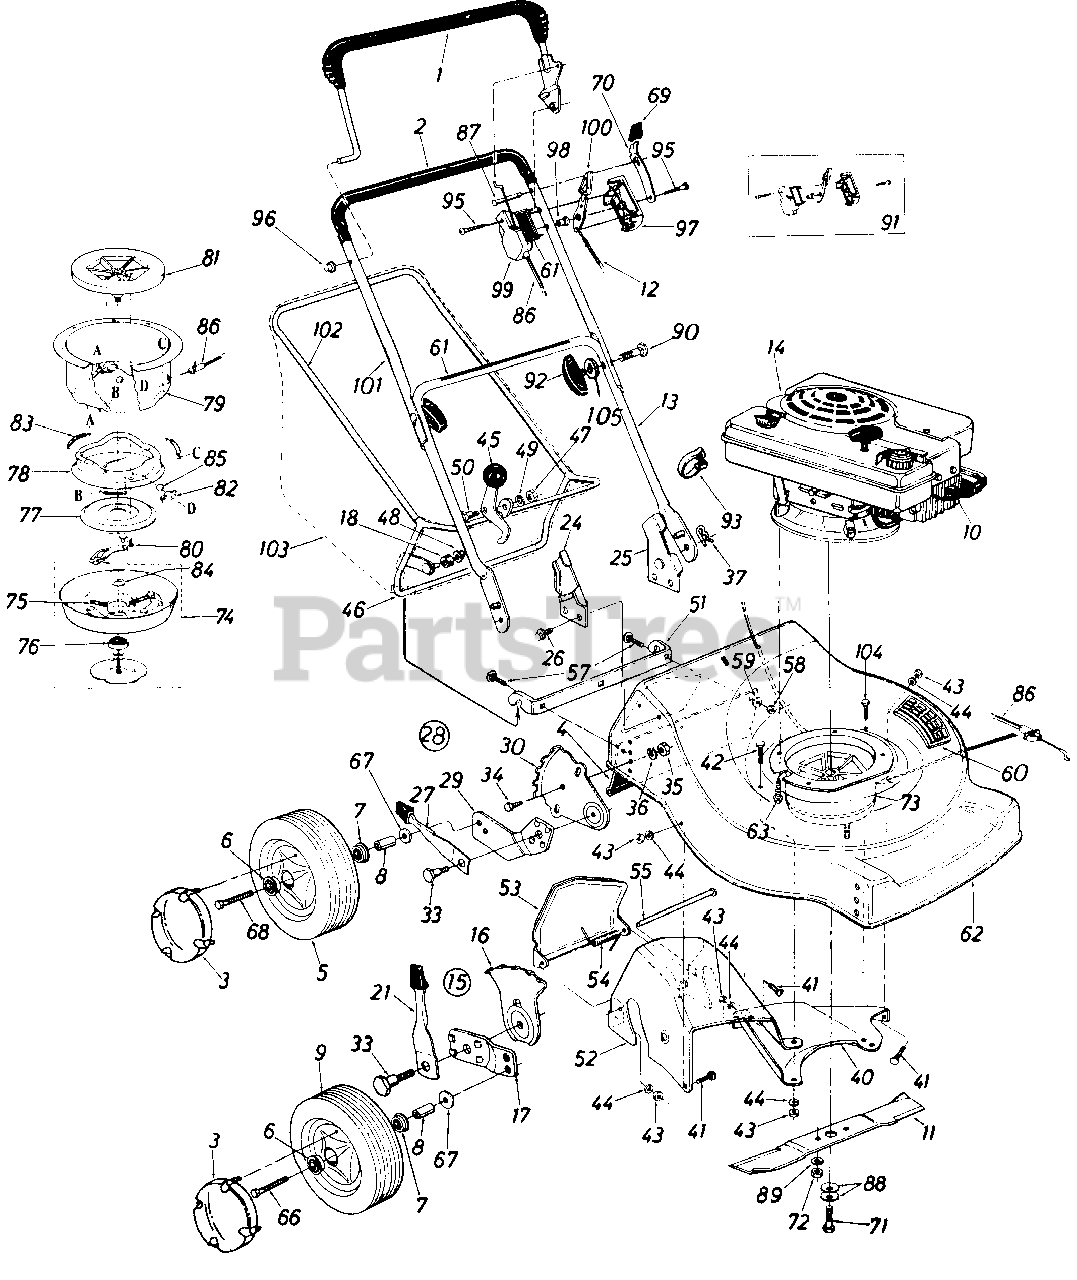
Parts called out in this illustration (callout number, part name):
1	Control Handle Ass'y. L.H.
3	Hub Cap
4	Rear Flap Ass'y.
5	Rear Wheel Ass'y. 8 x 1.75
6	Ball Bearing 3/8" I.D.
7	Ball Bearing 1/2" I.D.
8	Spacer 3/8" 1 .D.
9	Front Wheel Ass'y. 8 x 1.75
10	Spark Plug Boot
11	20" Blade
12	Throttle Wire 43"
13	Lower Handle
15	Height Adj. Ass'y. R.H.
16	Front Index Plate
17	Front Pivot Bar
18	Plastic Roller
21	Spring Lever w/Knob
24	Handle Brk't. Ass'y. R.H.
25	Handle Brk't. Ass'y. L.H.
26	Hex Wash. Hd. AB-Tap Scr. 1/4" x .62" Lg.
27	Spring Lever w/Knob
28	Height Adj. Assy. R.H.
29	Rear Pivot Bar R.H.
30	Rear Index Plate
33	Shld. Bolt .500" Dia. x .375" Lg.
34	Hex Wash. Hd. Tap Scr. 1/4 x .62" Lg.
35	Hex Nut 3/8-16 Thd.*
36	L-Wash. 3/8 I.D.*
37	Hairpin Cotter
40	Rear Chute Baffle L.H.
41	Carr. Bolt 1/4-20 x .50" Lg.
42	Hex Bolt 1/4-20 x .88" Lg.*
43	Hex Nut 1/4-20 Thd.*
44	L-Wash. 1/4" I.D.*
45	Cam Lever Ass'y.
46	Grass Catcher Lower Frame Ass 'y.
47	Hex Nut 5/16-18 Thd.*
48	Push Cap 3/8 Rod
49	L-Wash. 5/16" I.D.*
50	Shld. Bolt .437" Dia. x .180
51	Hitch Brk't.
52	Rear Chute Ass'y.
53	Chute Door
54	Torsion Spring
55	Hinge Pin
57	Carr. Bolt 1/4-20 x .75" Lg.
58	Sems Nut 1/4-20 Thd.
59	Fl-Wash. .285" I.D. x 1.25"
60	Foot Pad
61	Control Labels
66	Hex Scr. 3/8-16 x 1.75" Lg.
67	Bell-Wash. .400" I.D. x .88"
68	Hex Bolt 3/8-16 x 1.75" Lg.
69	Spring Lever Knob
70	Lockout Spring
71	Hex Cl-Scr. 3/8-24 x 2.0" Lg.
72	Hex Nut 3/8-24 Thd.
73	Blade Brake/Clutch Ass'y. Comp.
74	Clutch Blade Housing Ass'y.
75	Compression Spring
76	Ball Bearing .669" I.D.
77	Clutching Cone
78	Brake Cup Cone
79	Clutch Housing
80	Hex Wash. TT-Tap Cl-Scr. 1/4-20 x .75" Lg.
81	Fan Adapter
82	Ball Block
83	Extension Spring
84	Fl-Wash. .690" I.D. x 1.06"
85	Steel Ball .500" Dia.
86	Clutch Cable 46"
87	Lock Pin
88	Bell-Wash. .400" I.D. x .88"
89	L-Wash. 3/8" I.D.
90	Carr. Bolt 5/16-18 x 1.75" Lg.
91	Kit Control Housing Comp.
92	Hand Knob
93	Cable Tie
95	Truss Mach. Hi-B Tap Scr. #12 x 1.5" Lg.
96	Push Cap 5/16" Rod
97	Control Panel Half
98	Conrol Disc Pin
99	Clutch Panel Half
100	Throttle Control Lever
101	Upper Handle
102	Grass Catcher Upper Frame
103	Grass Bag
104	Hex Wash. Hd. Self-Tap Scr. 1/4-20 x .75" Lg.
105	Bell-Wash. 5/16" I.D.
